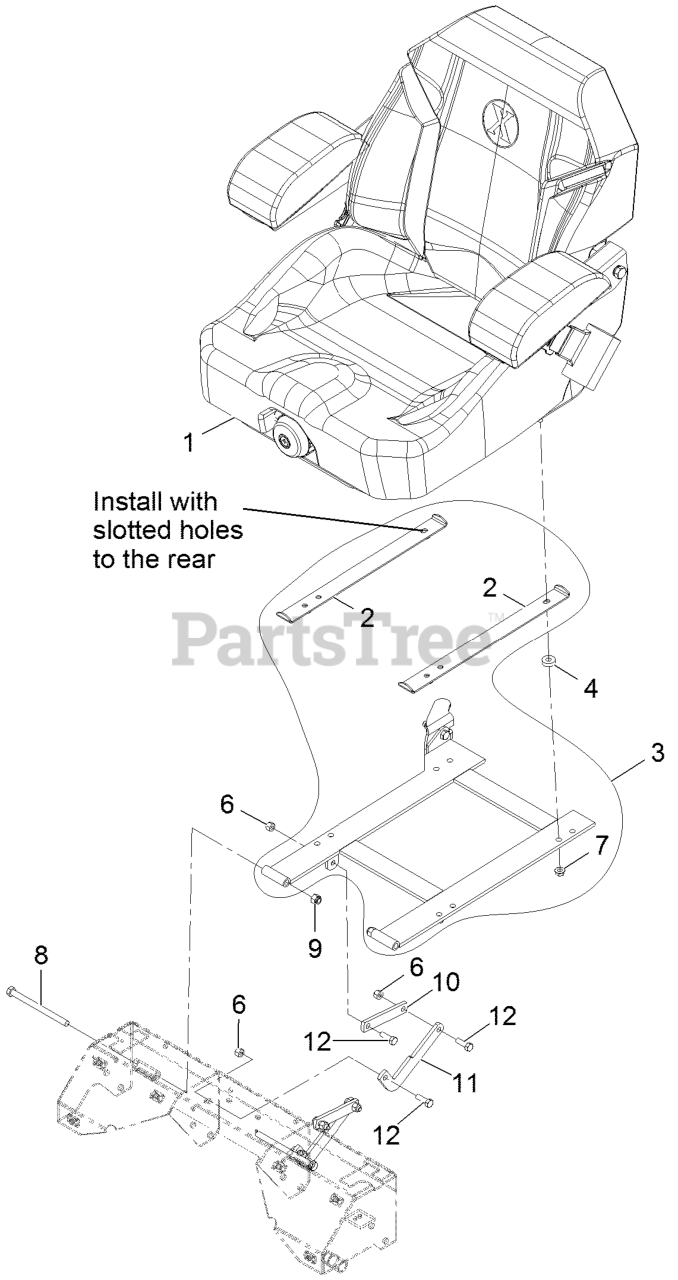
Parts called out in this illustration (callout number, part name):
1	KIT-SUSPENSION SEAT
2	STOP/SPACER-SEAT
3	KIT,SEAT FRAME SERVICE
6	NUT-LOCK, NI
8	SCREW-HH
9	NUT-LOCK, NI
10	LINK-STOP, SEAT
11	LINK-STOP, SEAT
12	SCREW-HH
